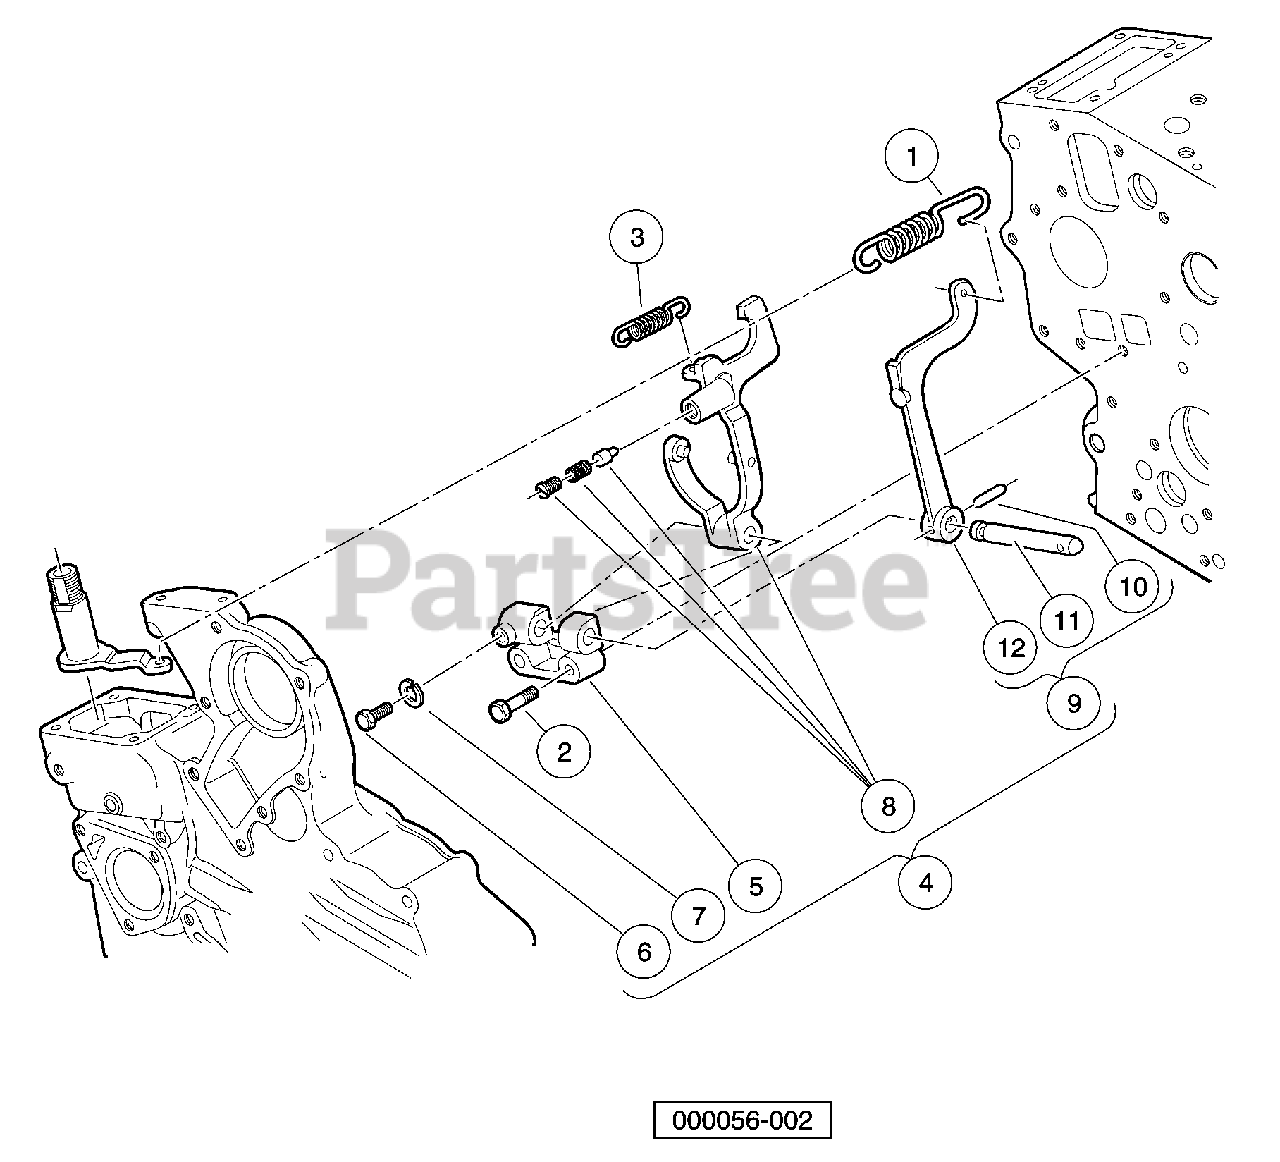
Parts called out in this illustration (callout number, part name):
1	SPRING, GOVERNOR
2	BOLT, M5X0.75X25
3	SPRING-START
4	ASSY, GOV FORK, D722 CB
5	HOLDER, FORK LEVER
6	BOLT, M5X0.75X11
7	WASHER, SPRING, M5
8	Lever, Fork, Middle, D722 CB.
9	Assembly, Governor Fork Level, Lower, D722 CB
10	PIN, SPRING
11	SHAFT, FORK LEVER
12	Lever, Fork, End, D722 CB.
